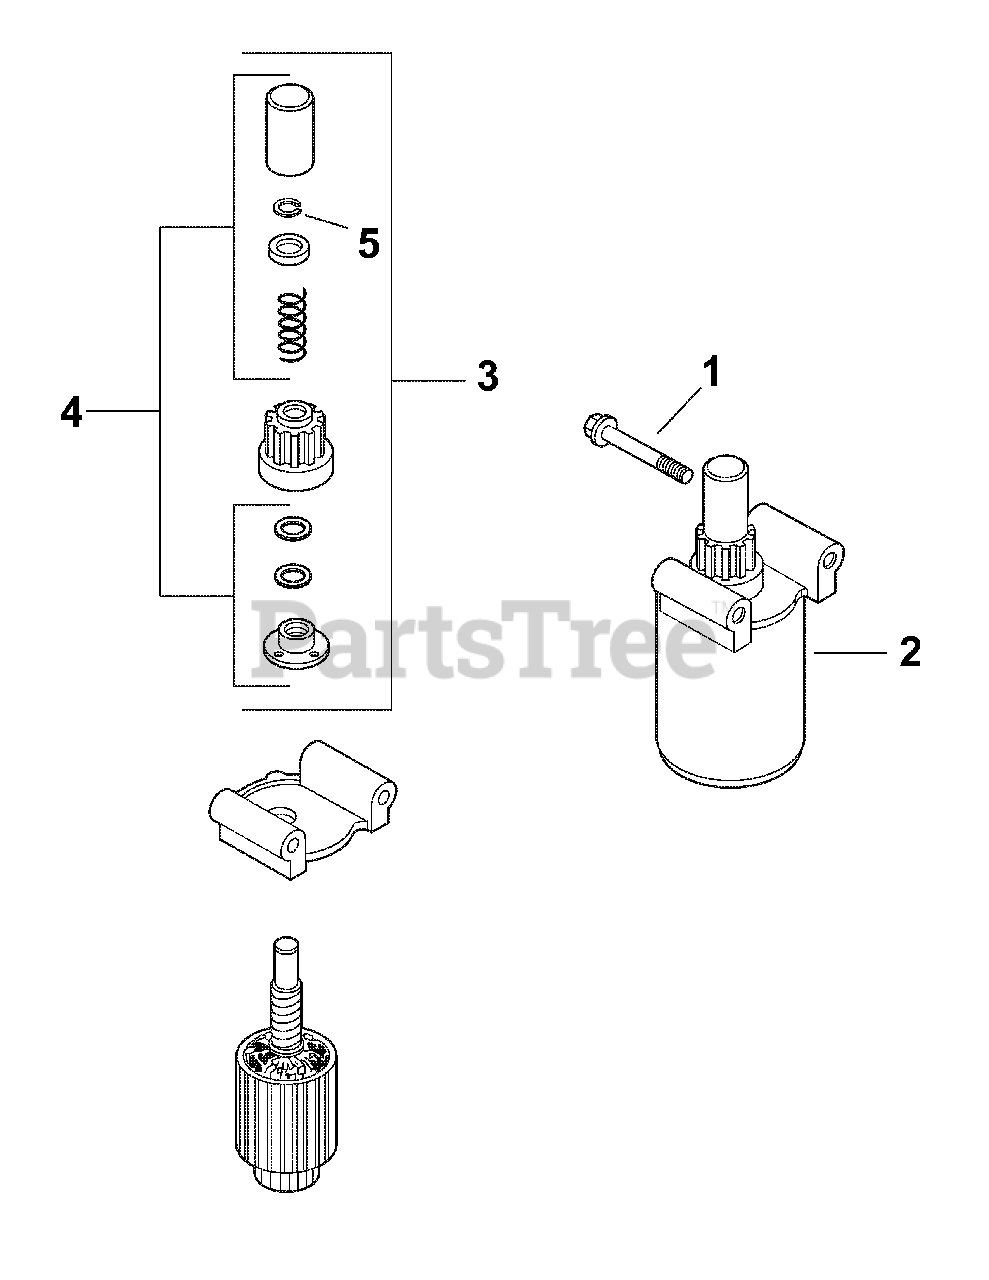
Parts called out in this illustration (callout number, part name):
1	Flg. Screw, M8 X 1.25 X 80
2	Starter Assembly
4	Kit, Drive Parts
5	Ring, Retaining
